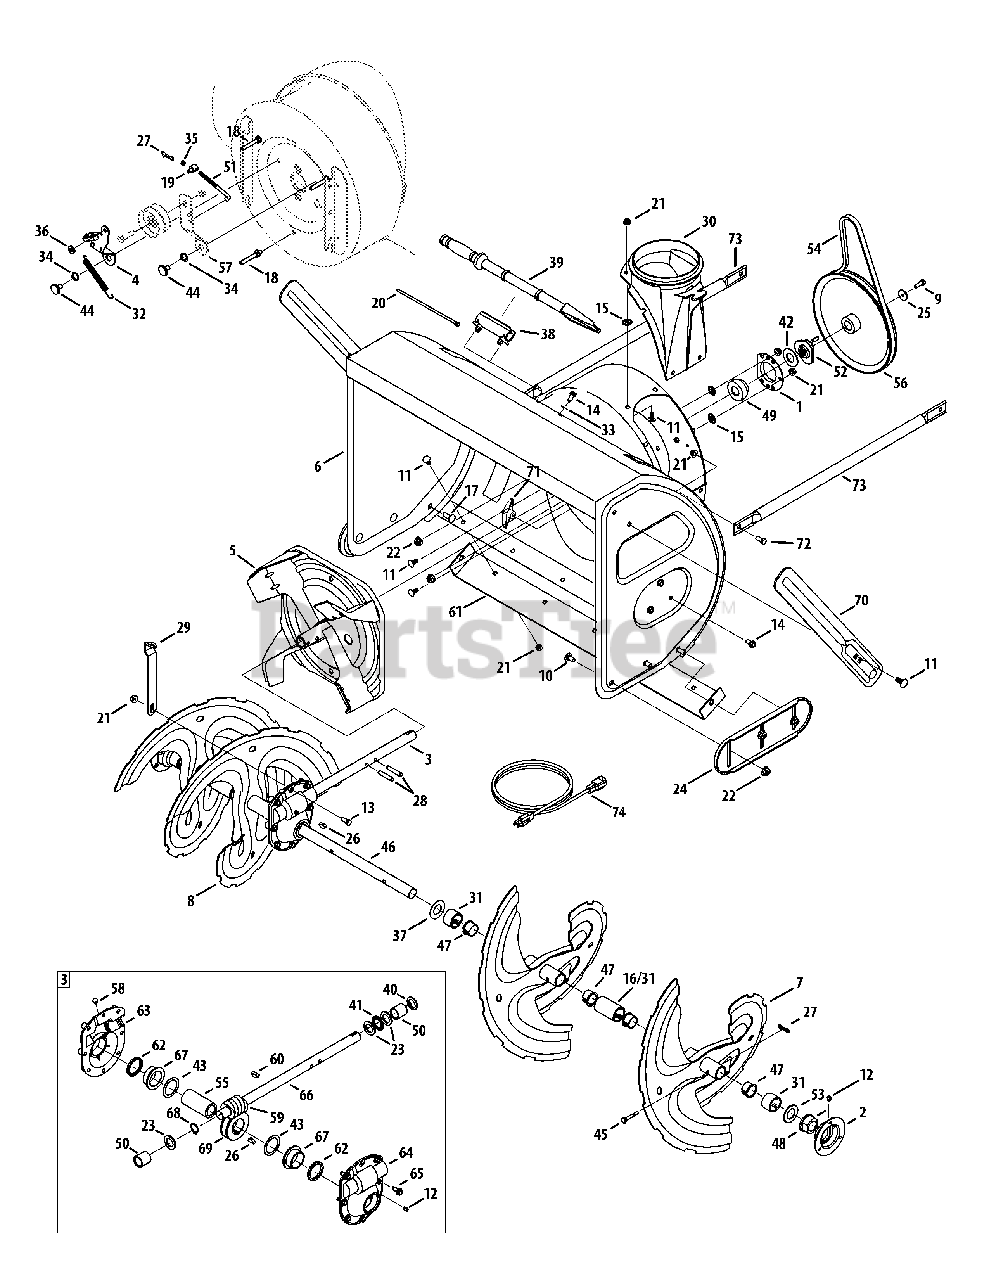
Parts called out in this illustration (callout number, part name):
1	Housing, Bearing
2	Housing, Bearing
3	Gear Box Assembly
4	Bracket Assembly, Auger Brake
5	Impeller, 16"
6	Housing, Auger, 33"
6	Housing, Auger, 30"
6	Housing, Auger, 28"
7	Spiral Assembly, LH
8	Spiral Assembly, RH
9	Screw, Hex Cap Lock, 5/16-24
10	Screw, Carriage, 3/8-16 x .75
11	Screw, Carriage, 5/16-18 x .75
12	Fitting, Lube
13	Screw, Hex Cap, 5/16-18 x 1.0 Gr5
14	Screw, 5/16-18 x .750
15	Nut, Push
16	Spacer, 1.0 x 1.5 x 2.5 Lg
17	Screw, Carriage, 3/8-16 x 1.00
18	Screw w/Stud, 5/16-18 x .4300
19	Ferrule
20	Tie Strap
21	Nut, Hex Flange Lock, 5/16-18
22	Nut, Hex Flange Lock, 3/8-16
23	Wash, Flat, .88 ID x .38 OD
24	Skid Shoe
25	Washer, Flat, .34 x 1.5 x .15 Ht.
26	Key, Woodruff, 1/4 x 3/4
27	Pin, Bow-tie Cotter
28	Pin, Spiral, 5/16 x 1.75
29	Bracket, Gear Box Support
30	Adapter, Chute, 6"
31	Spacer, 1.0 x 1.5 x 1.0 Lg
32	Spring, Extension
33	Washer, Flat, .349 x .879 .063
34	Washer, Wave, .625 x .885 x .015
35	Jam Nut, 5/16-18
36	Washer, .344 x .75 x .12
37	Washer, 1.01 x 1.86 x .06
38	Clip, Mounting
39	Tool, Clean-out
40	Seal, Oil
41	Bearing, Thrust
42	Washer, Flat, .76 x 1.49 x .06
43	Wash, Flat, 1.52ID x 2.0 OD
44	Screw, Shoulder, .625 x .17
45	Pin, Shear, .25 x 1.75
46	Shaft, Spiral, 33"
46	Shaft, Spiral, 30"
46	Shaft, Spiral, 28"
47	Bushing, Flange,
48	Bearing, Flange w/Flats
49	Bearing, Self Aligning
50	Sleeve
51	Rod, Auger Idler
52	Adapter, Pulley w/Pins
53	Spacer, 1.004 x 1.375 x .25
54	V-Belt, 1/2 x 42
55	Shaft, Gear, Worm
56	Pulley, Auger Drive, 10.0
57	Bracket, Auger Idler
59	Gear, Worm
60	Key, Hi Pro, 3/16 x 3/4
61	Plate, Shave, 33"
61	Plate, Shave, 30"
61	Plate, Shave, 28"
62	Oil Seal
63	Hsg, Ass’y, Auger RH (Incl. Ref. 62 & 67)
64	Hsg, Ass’y, Auger LH (Incl. Ref. 62 & 67)
65	Screw, LD, 5/16-18 x .750
66	Shaft, Drive, Auger
67	Flange Bearing
68	External, Retaining, Ring
69	Gear, Worm, LH
70	Blade Guide
71	Wing Knob
72	Screw, 5/16-18 x .75 GR5
73	Tube, Support
74	Extension Cord, 110V
